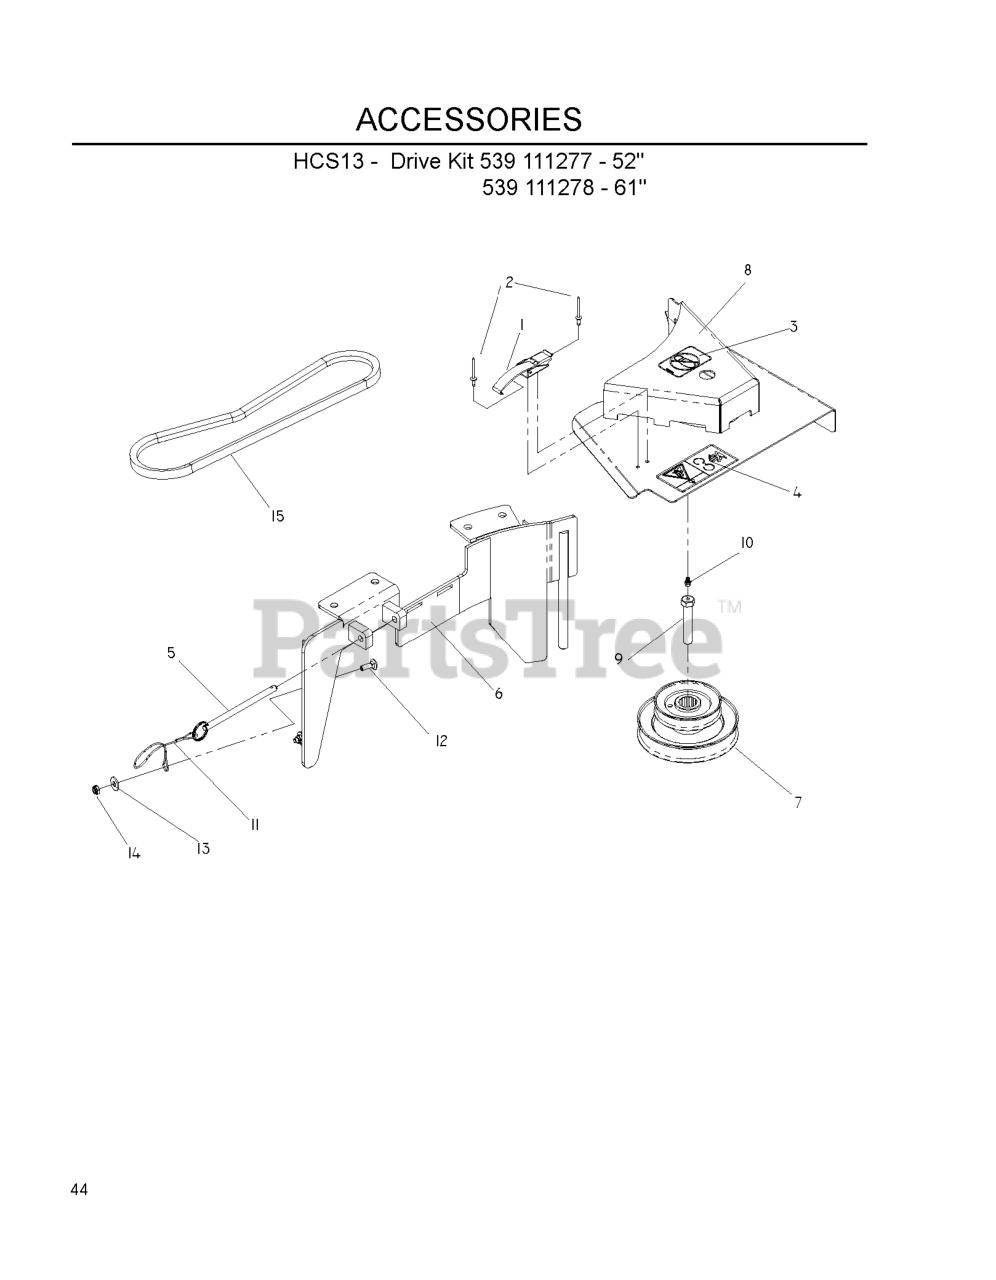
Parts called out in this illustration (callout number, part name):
1	DRAW LATCH
2	RIVET, BLIND, 5/32 DIA
3	DECAL, NO STEP
4	DECAL, BELT DRIVE
6	BLOWER DECK PLATE WLDMNT, 61"
7	61 LNG DBL HEX STK PULLEY
8	BELT SHIELD ASSY 61"
9	HCS, 7/16-20 X 2 1/2, GR8
10	ZERK
12	RHSNB 1/4C X 3/4
13	WASHER 1/4 FLAT
14	JAM NUT 1/4C (2 2 PW01)
15	BELT
